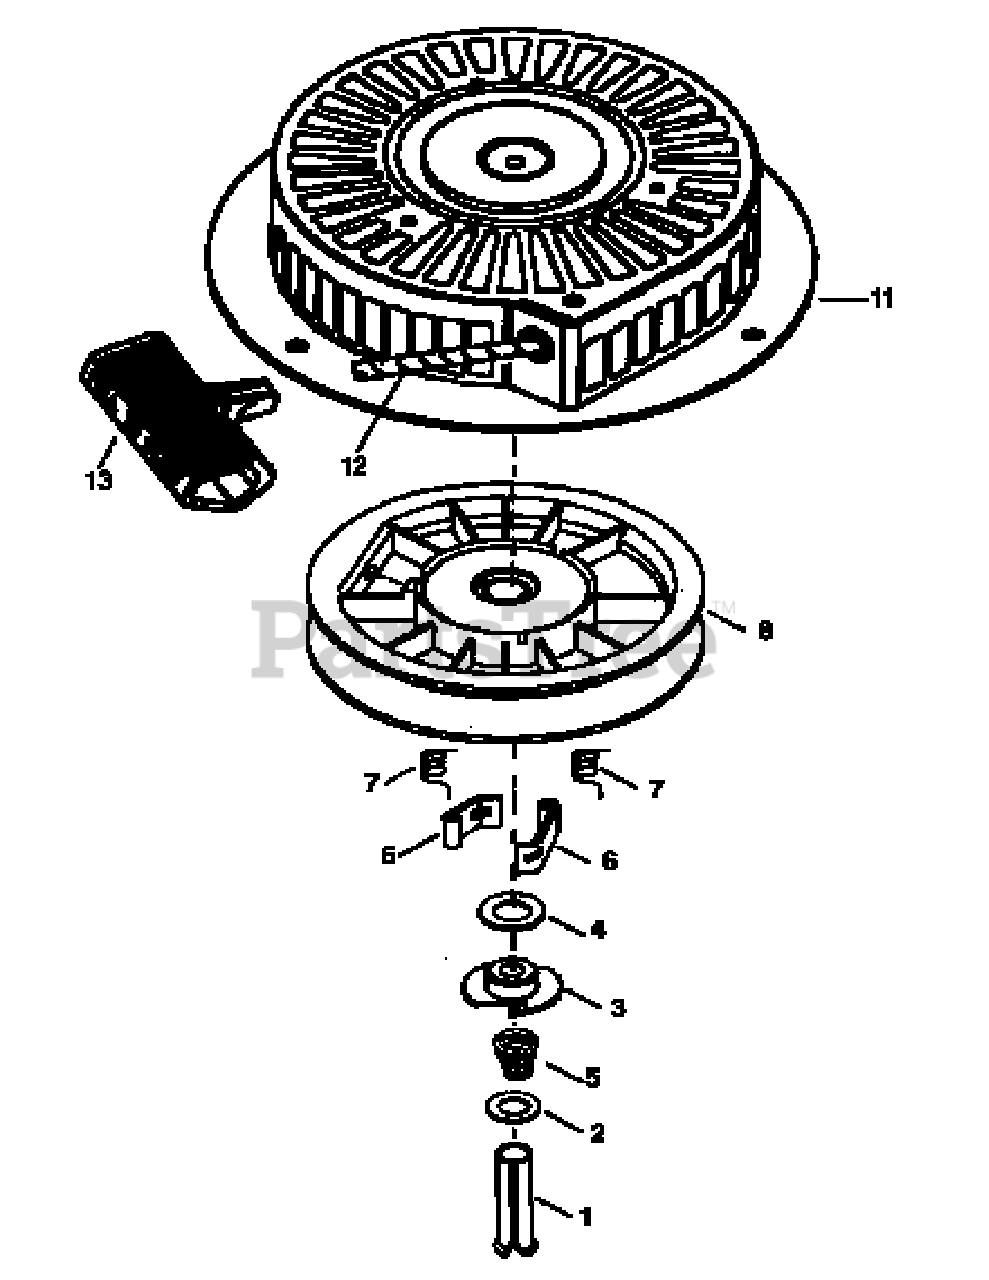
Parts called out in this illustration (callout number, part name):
5	Brake Spring
6	Starter Dog
7	Dog Spring
8	Pulley & Rewind Spring Assy.
11	Starter Housing Assy.
12	Starter Rope
13	Mitten Grip Handle
